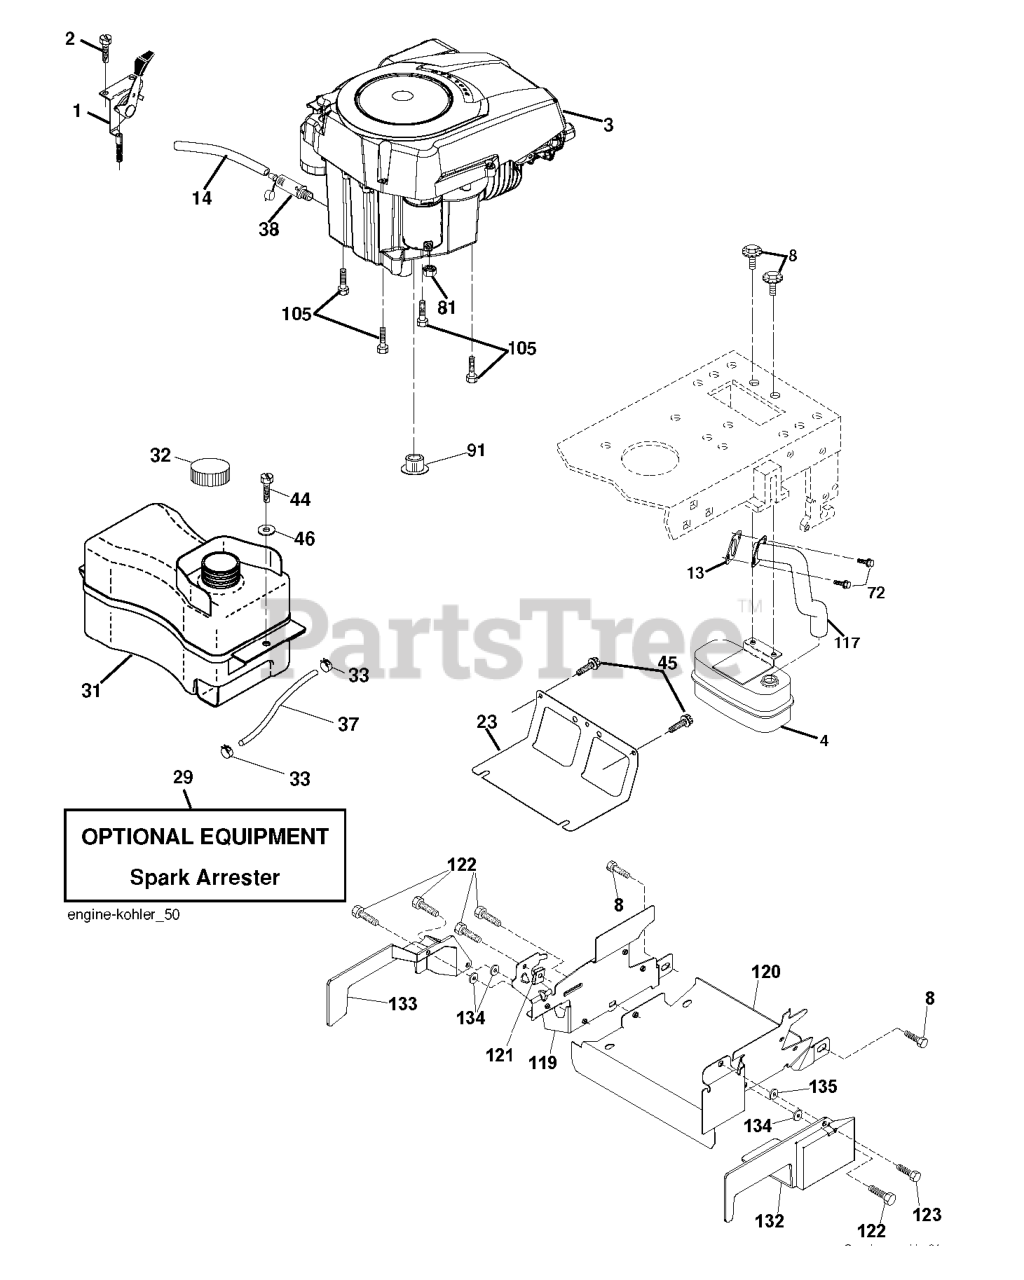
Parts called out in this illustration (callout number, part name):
1	CONTROL.TH/CK.C.
2	SCREW.#10 X 0.750.BOS
4	MUFFLER.SINGLE.CYL.KOHL/B&S
8	BOLT.5/16-18UNCX3/4 W/SEMS.BLK
13	GASKET.EXHAUST.KOHLER
14	TUBE, DRAIN OIL ASM.
23	SHIELD.BROWNING.DBR.GUARD
29	KIT.SPARK ARRESTOR 794945 B&S
31	RP TANK FUEL FRT 1.5 GAL
32	FUEL CAP
33	HOSE CLAMP
37	LINE.FUEL.20
38	PLUG DRAIN OIL EASY
44	SCREW HEXWSHR 1/4-20X3/4
45	SCREW, 3/8-16X3/4
72	SCREW.SOCKET HD.5/16-1
81	NUT
91	BUSHING.1.375OD
105	SCREW 3/8-16X1
117	RP.TUBE.EXHAUST.KOHL.COURAGE
119	LENKRAD
120	GUARD 532199767
122	SCREW.1/4-20X5/8
123	SCREW, 5/16-18 X 1/2
132	SHIELD RIGHT
133	SHIELD LEFT
134	PALNUT 1/4
135	WASHER 5/16"
